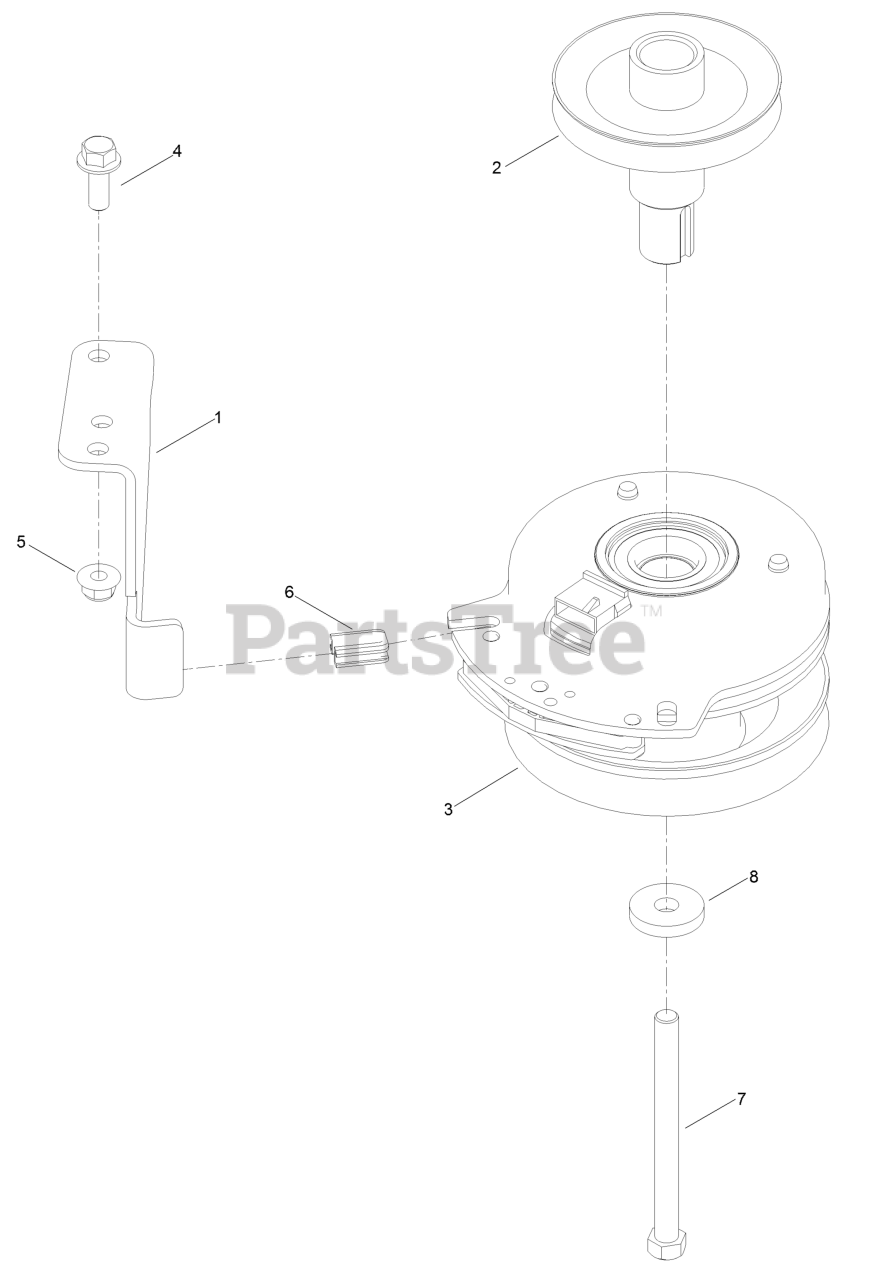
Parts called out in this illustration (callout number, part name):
1	Stop-Clutch (Wide)
2	Pulley-Engine
3	Clutch-PTO
4	Screw-HHF
5	Nut-HF, NI
6	Isolator-Clutch
7	Screw-HH
8	Washer
